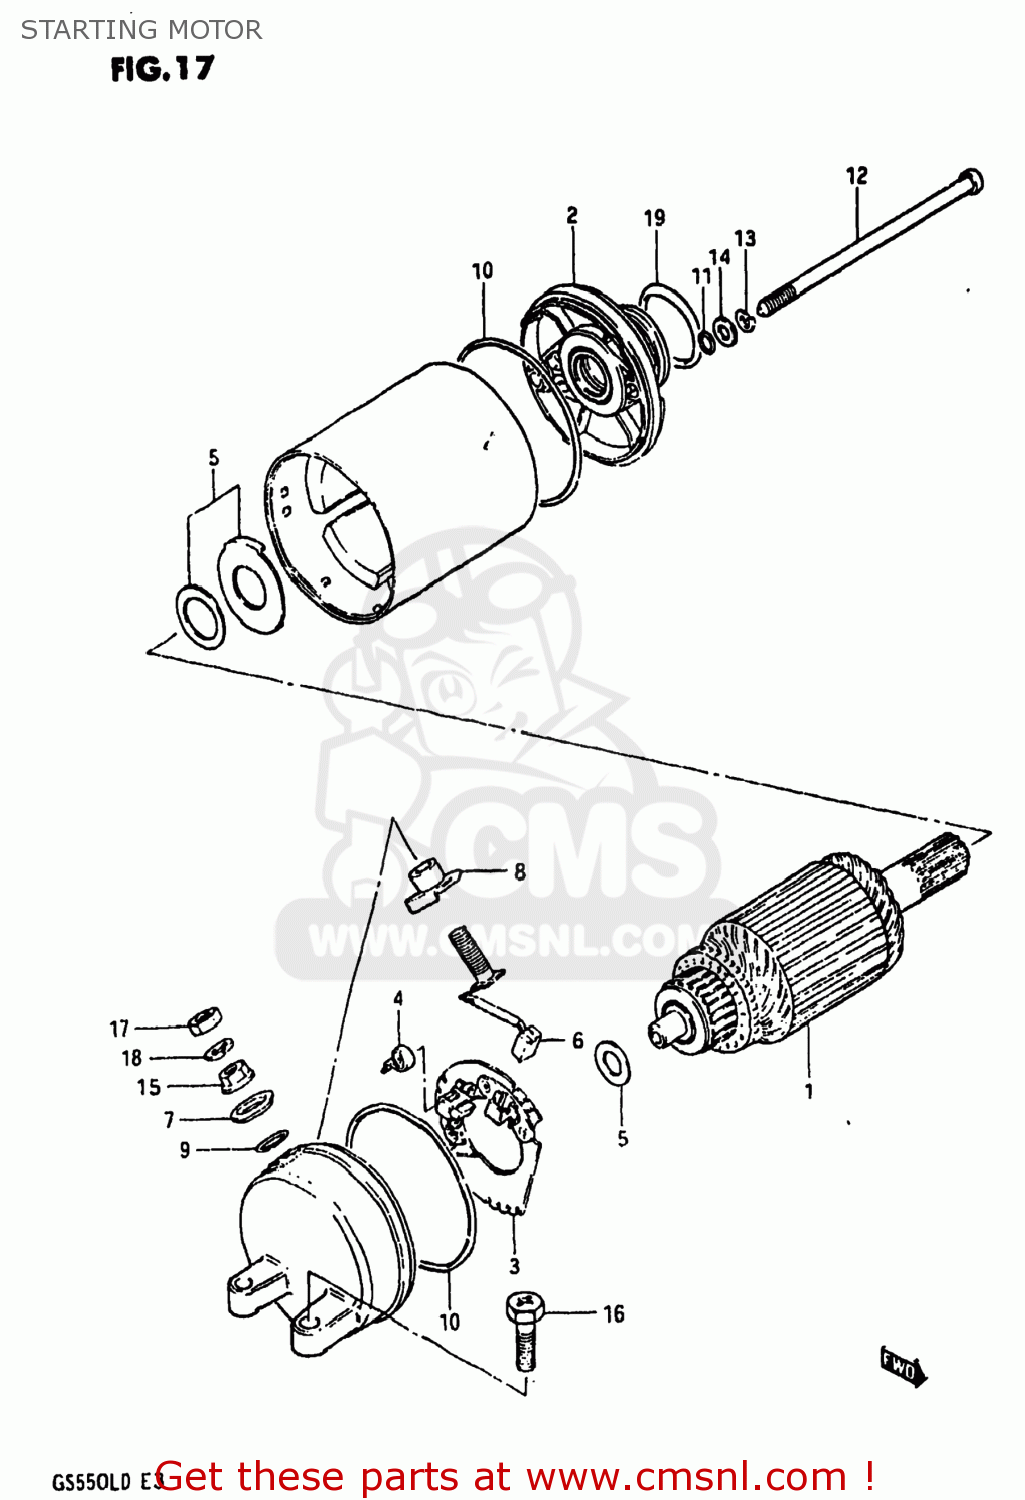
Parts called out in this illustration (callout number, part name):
1	ARMATURE
2	BRACKET SET,STARTING MOTOR
3	HOLDER,BRUSH
4	SPRING
5	SHIM SET,STARTING MOTOR
6	BRUSH SUB ASSY,STARTING MOTOR
7	BUSHING
8	BUSH,B
9	O RING
10	O RING
11	O RING
12	BOLT
13	LOCK WASHER
14	WASHER
15	NUT
16	BOLT
17	NUT 6MM
18	LOCK WASHER
19	O RING(D:3,ID:24.5)
